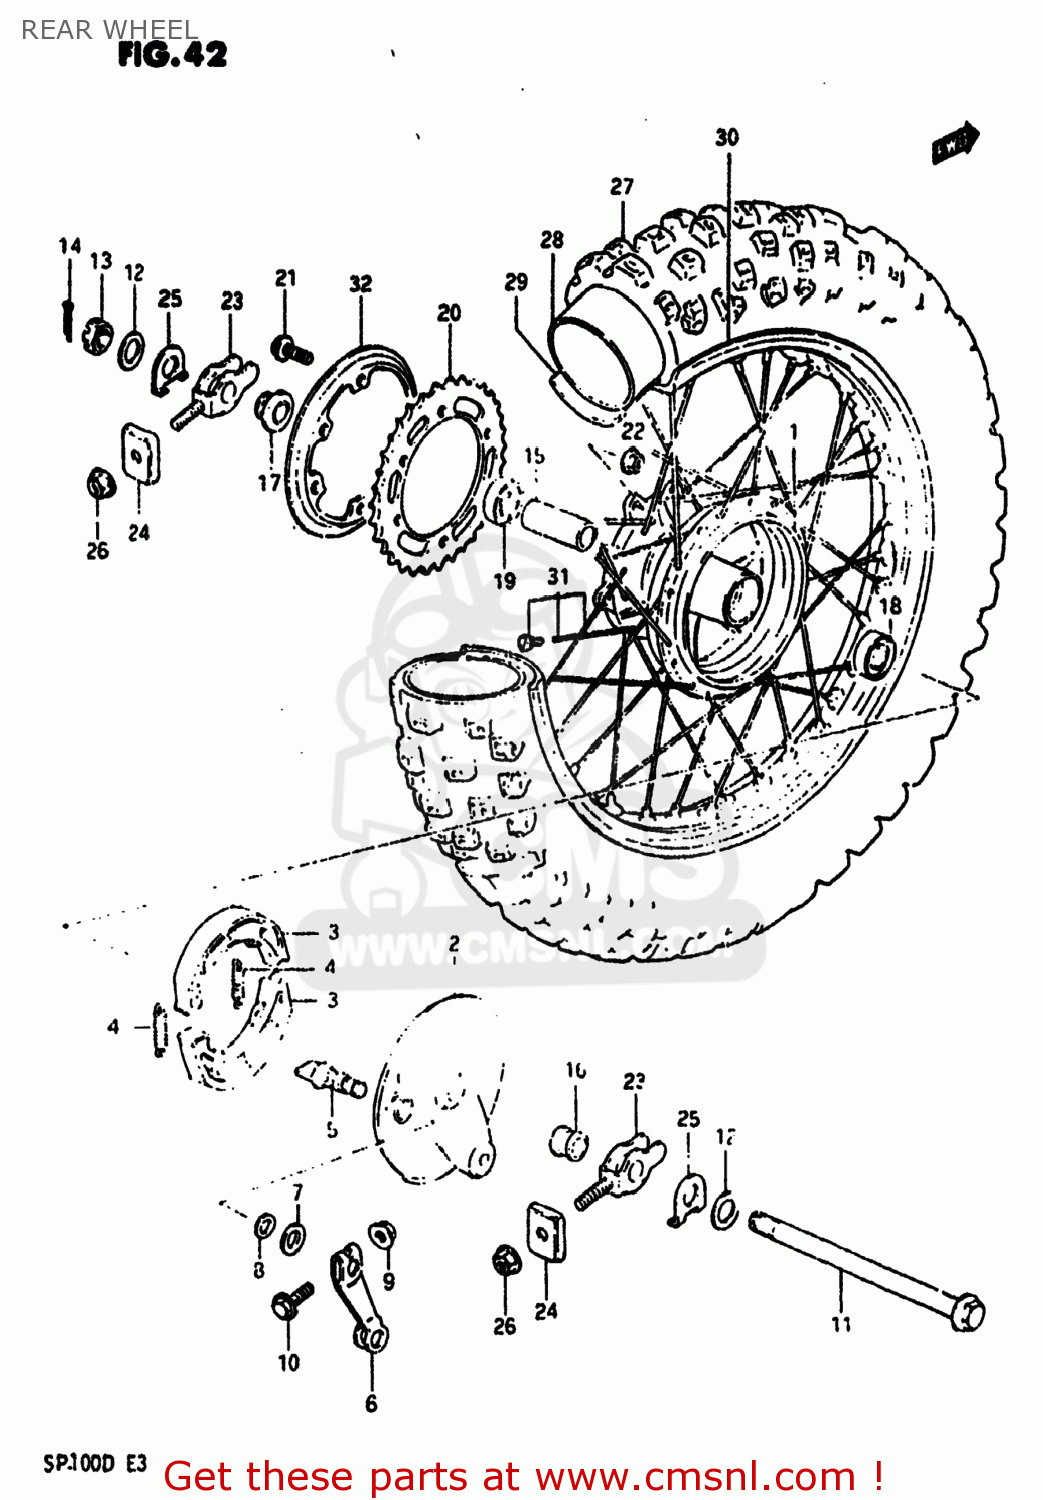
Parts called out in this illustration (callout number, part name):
1	HUB,RR WHEEL
2	PANEL,REAR HUB
3	SHOE,BRAKE
4	SPRING(L:34)
5	CAM,FRONT BRAKE
6	LEVER,RR BRAKE CAM
7	WASHER (14.5X22X1.6)
8	O-RING (D:2.4 ID:13.8)
9	NUT
10	BOLT 6X35
11	AXLE,REAR
12	WASHER
13	NUT
14	COTTER PIN
15	SPACER(15.3X21.7X97)
16	SPACER,REAR AXLE
17	SPACER,REAR AXLE
18	BEARING
19	BEARING
20	SPROCKET,REAR
21	BOLT(8X33)
22	NUT
23	ADJUSTER,CHAIN
24	ADJUSTER,CHAIN
25	WASHER,CHAIN ADJUSTER
26	NUT
27	TIRE
28	TUBE
29	PROTECTOR,WHEEL,INNER
30	RIM,REAR WHEEL
31	SPOKE SET,REAR
32	PLATE,CHAIN SIDE
